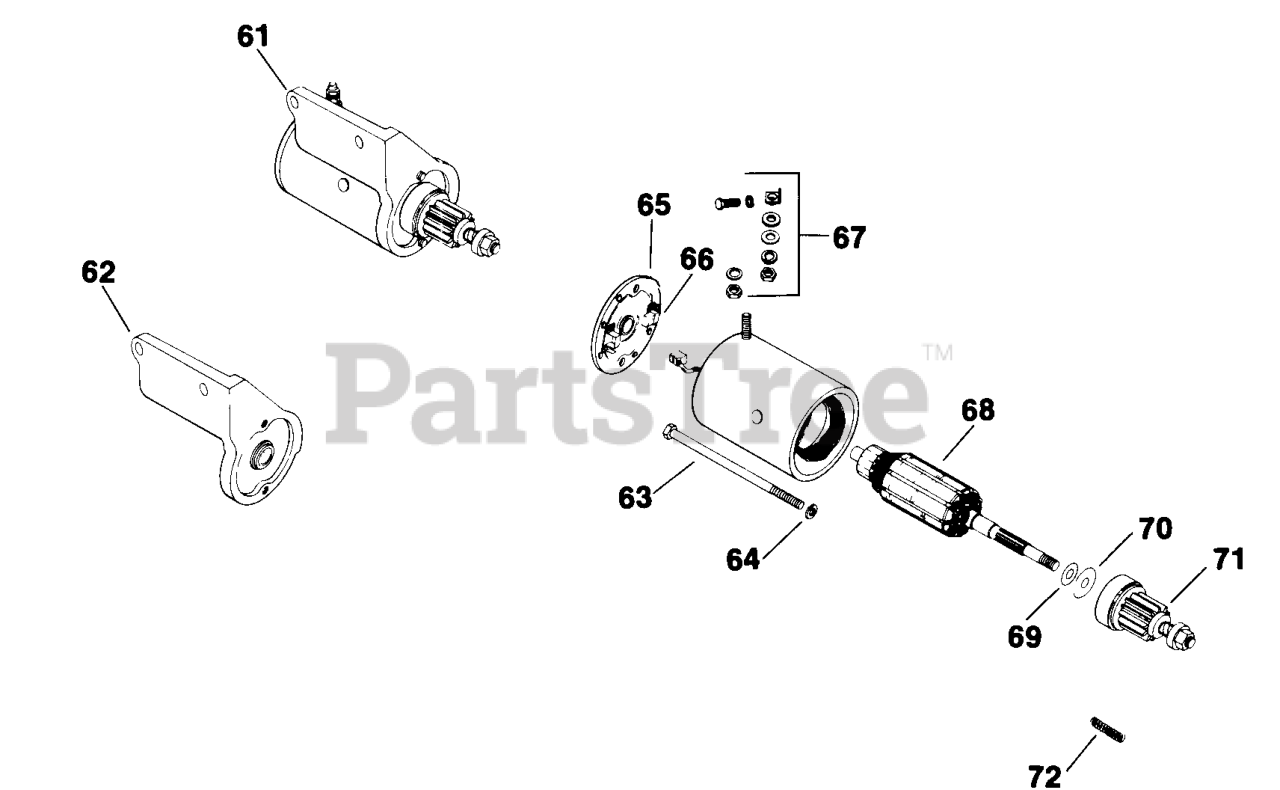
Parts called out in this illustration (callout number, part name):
61	STARTER - USE 41 098 03
62	KIT - DISCONTINUED
63	BOLT - DISCONTINUED
65	CAP - DISCONTINUED
66	KIT - DISCONTINUED
68	ARMATURE - DISCONTINUED
71	DRIVE - DISCONTINUED
